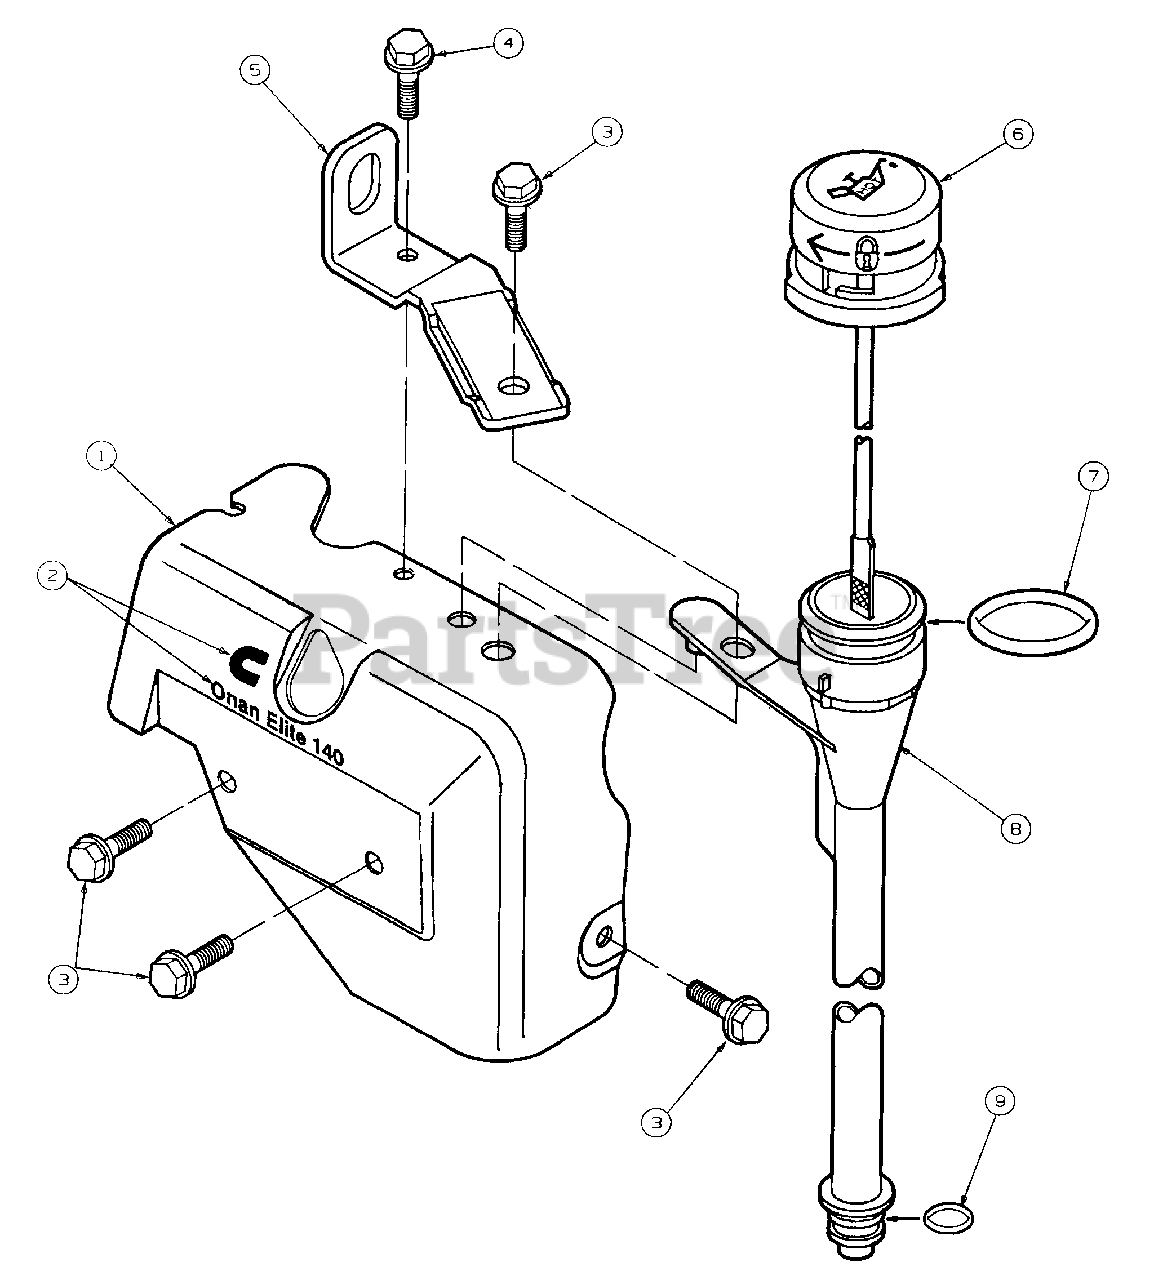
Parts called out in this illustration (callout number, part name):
1	Housing, Air Cylinder
2	Label, Model Ident
3	Screw, Hex Head Flange, Thread Forming
4	Screw, Flange Lock
5	Bracket, Lift
6	Indicator & Cap Assy
7	O-Ring, Upper
8	Tube, Oil Fill
9	O-Ring, Lower
